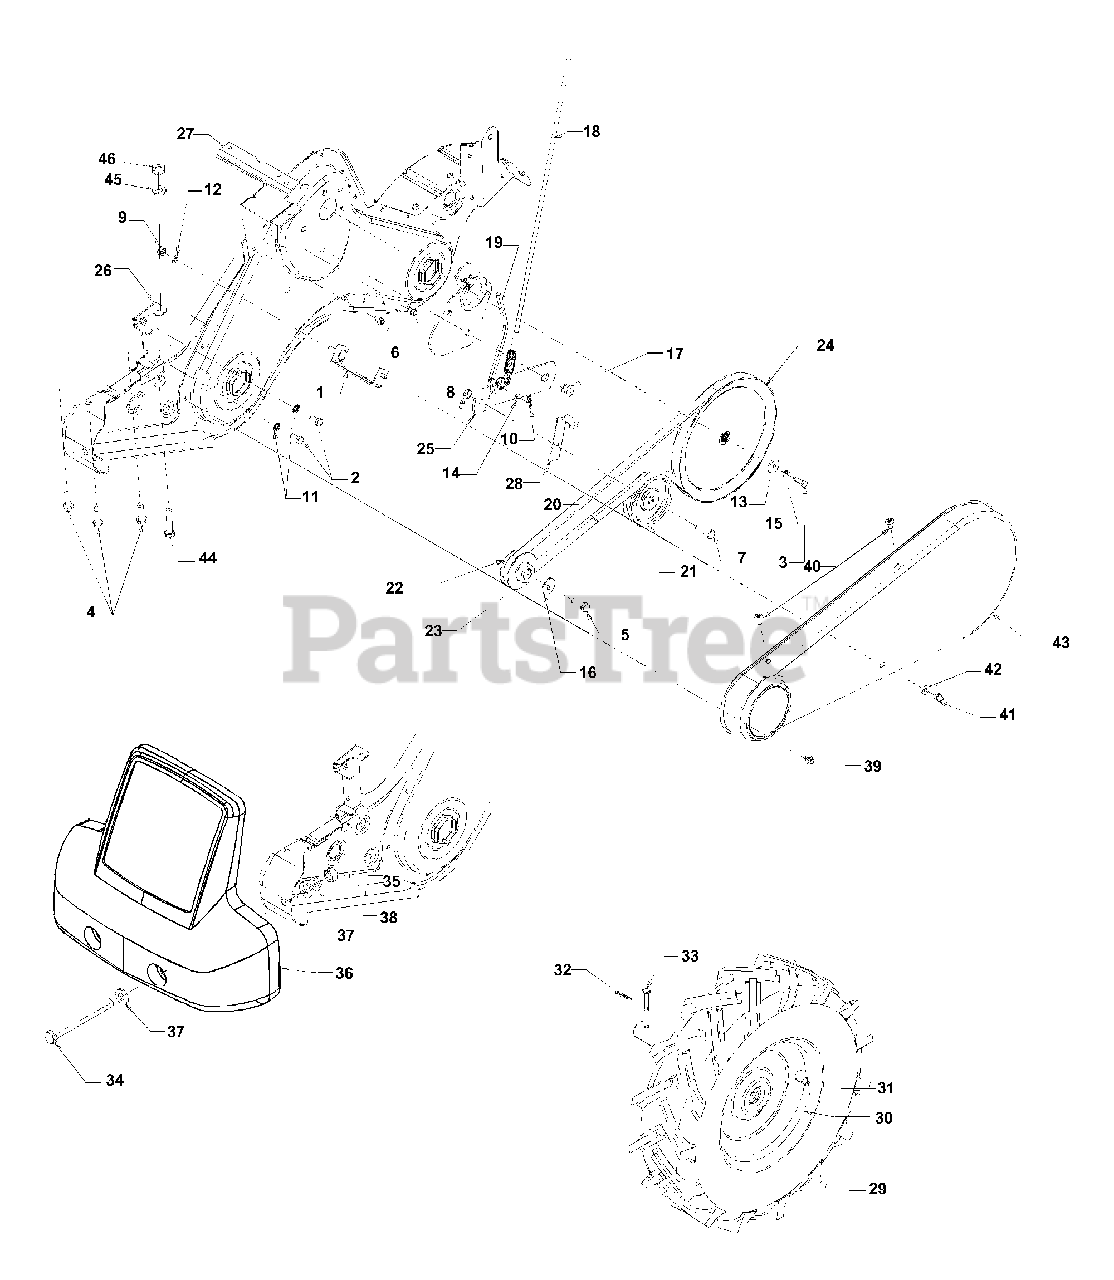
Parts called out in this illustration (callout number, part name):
1	Belt Cover Brkt. Ass'y
2	Hex Bolt 5/16-24 x .62" Lg.
3	Hex Bolt 1/4-28 x .75" Lg.
4	Hex Wash.TT-Sems Screw 3/8-16 x 1.250" Lg.
5	Hex Bolt 3/8-24 x 1.00
6	Hex Wash. Hd. S-Tap Scr.
7	Hex Cap Screw 3/8-16 x 1.25
8	Ctr. Lock Jam Nut 3/8-16
9	Hex Nut 5/16-18
10	Internal Cotter Pin
11	Hairpin Clip
12	L-Wash. 5/16" I.D.
13	Fl-Wash. 1/4 I.D. x .93 O.D.
14	Spring-Wash. .317 x .625 O.D. x .099
15	L-Wash. 1/4" I.D.
16	Bell-Wash. .396 x 1.140 x .095
17	Shld. Nut 7/16-20
18	Clutch Cable w/eyebolt
19	Idler Pulley Rod
20	Belt: 4L x 58.16 Lg.
21	Fl-Idler w/Flange 3.75" O.D.
22	Outer Engine Pulley Half
23	Inner Engine Pulley Half
24	Input Pulley
25	Idler Bracket
26	Belt Keeper Brkt.
27	Shift Cover Brkt.
28	Idler Belt Keeper
32	Clevis Pin
33	Internal Cotter Pin
34	Hex Bolt 1/2-13 x 5.00" Lg.
35	Hex Nut 1/2-13 Thd.
36	Counterweight
37	Fl-Wash. .510" I.D. x 1.0" O.D.
38	L-Wash. 1/2" Lg.
39	Hex Screw 1/4-20 x .375" Lg.
40	Screw 1/4-14 x .625" Lg.
41	Acorn Lock Nut
42	Fl-Washer 1/4 x .620" Lg.
44	Hex Bolt 5/16-18 x 1.50" Lg.
45	Bell-Wash .340 I.D. x .872 O.D.
46	Nut: Hex 5/16-18
